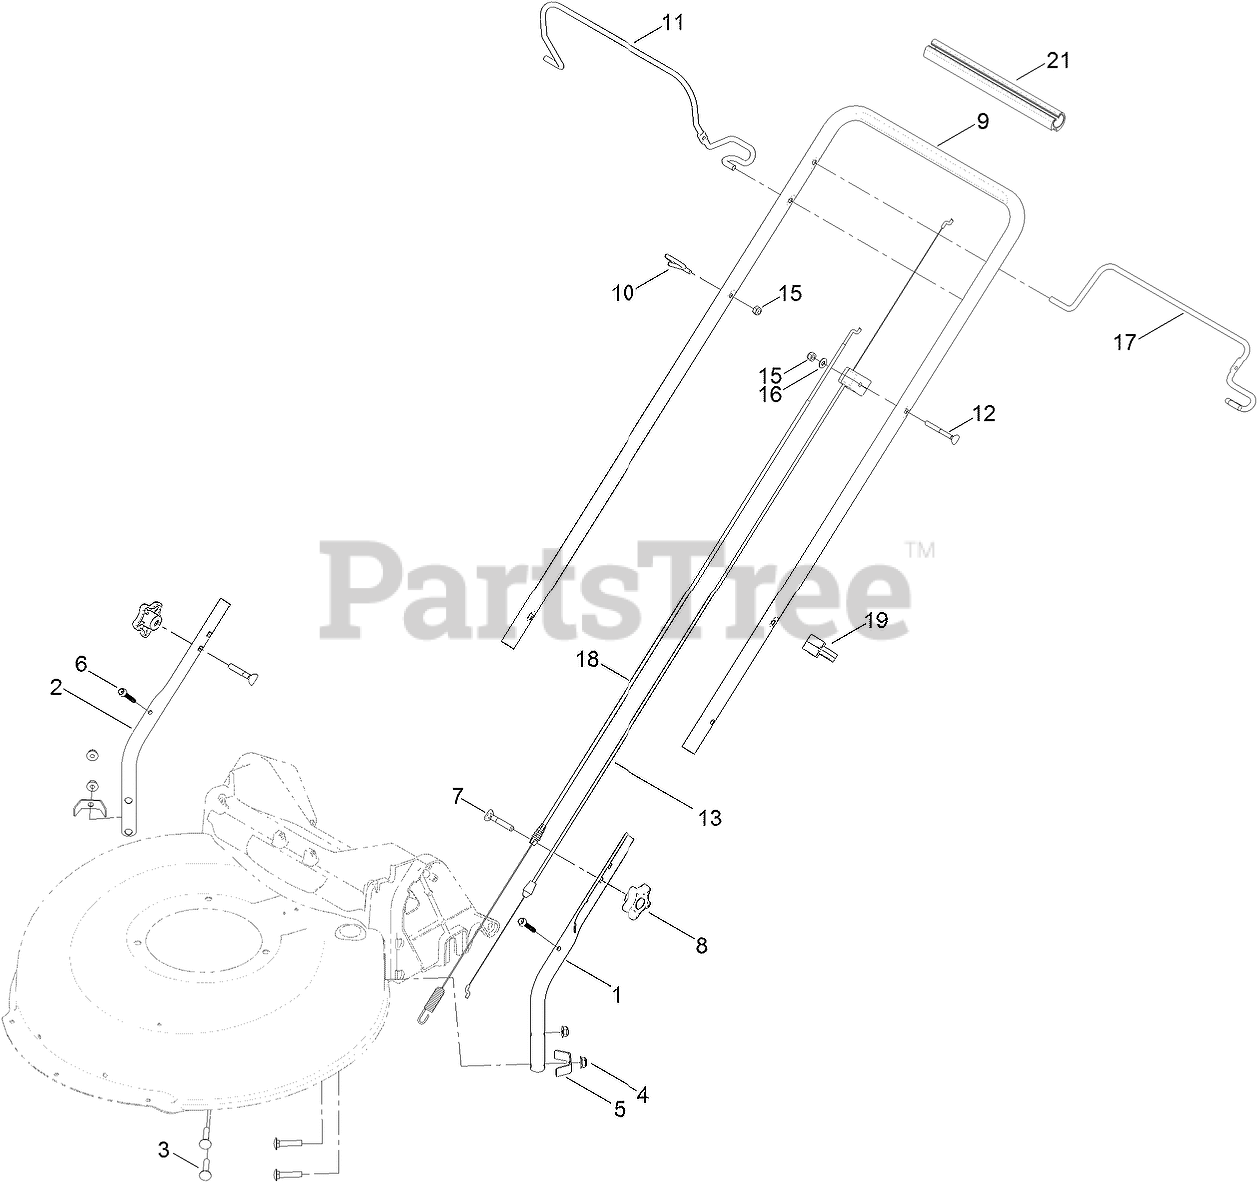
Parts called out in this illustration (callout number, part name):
1	HANDLE-LOWER, LH
2	HANDLE-LOWER, RH
3	BOLT-CARR
4	NUT-FLANGE, NI
5	BRACKET-CHUTE
6	SCREW-FLANGE, SERRATED
7	SCREW-HANDLE
8	KNOB-HANDLE
9	HANDLE-UPPER
10	GUIDE-ROPE
11	BAIL-BRAKE
12	SCREW-HANDLE
13	CABLE-BRAKE
15	NUT-LOCK, NI
16	WASHER-FLAT
17	BAIL-TRACTION
18	CABLE-TRACTION
19	GUIDE-CABLE
21	GRIP-HANDLE, COMFORT
